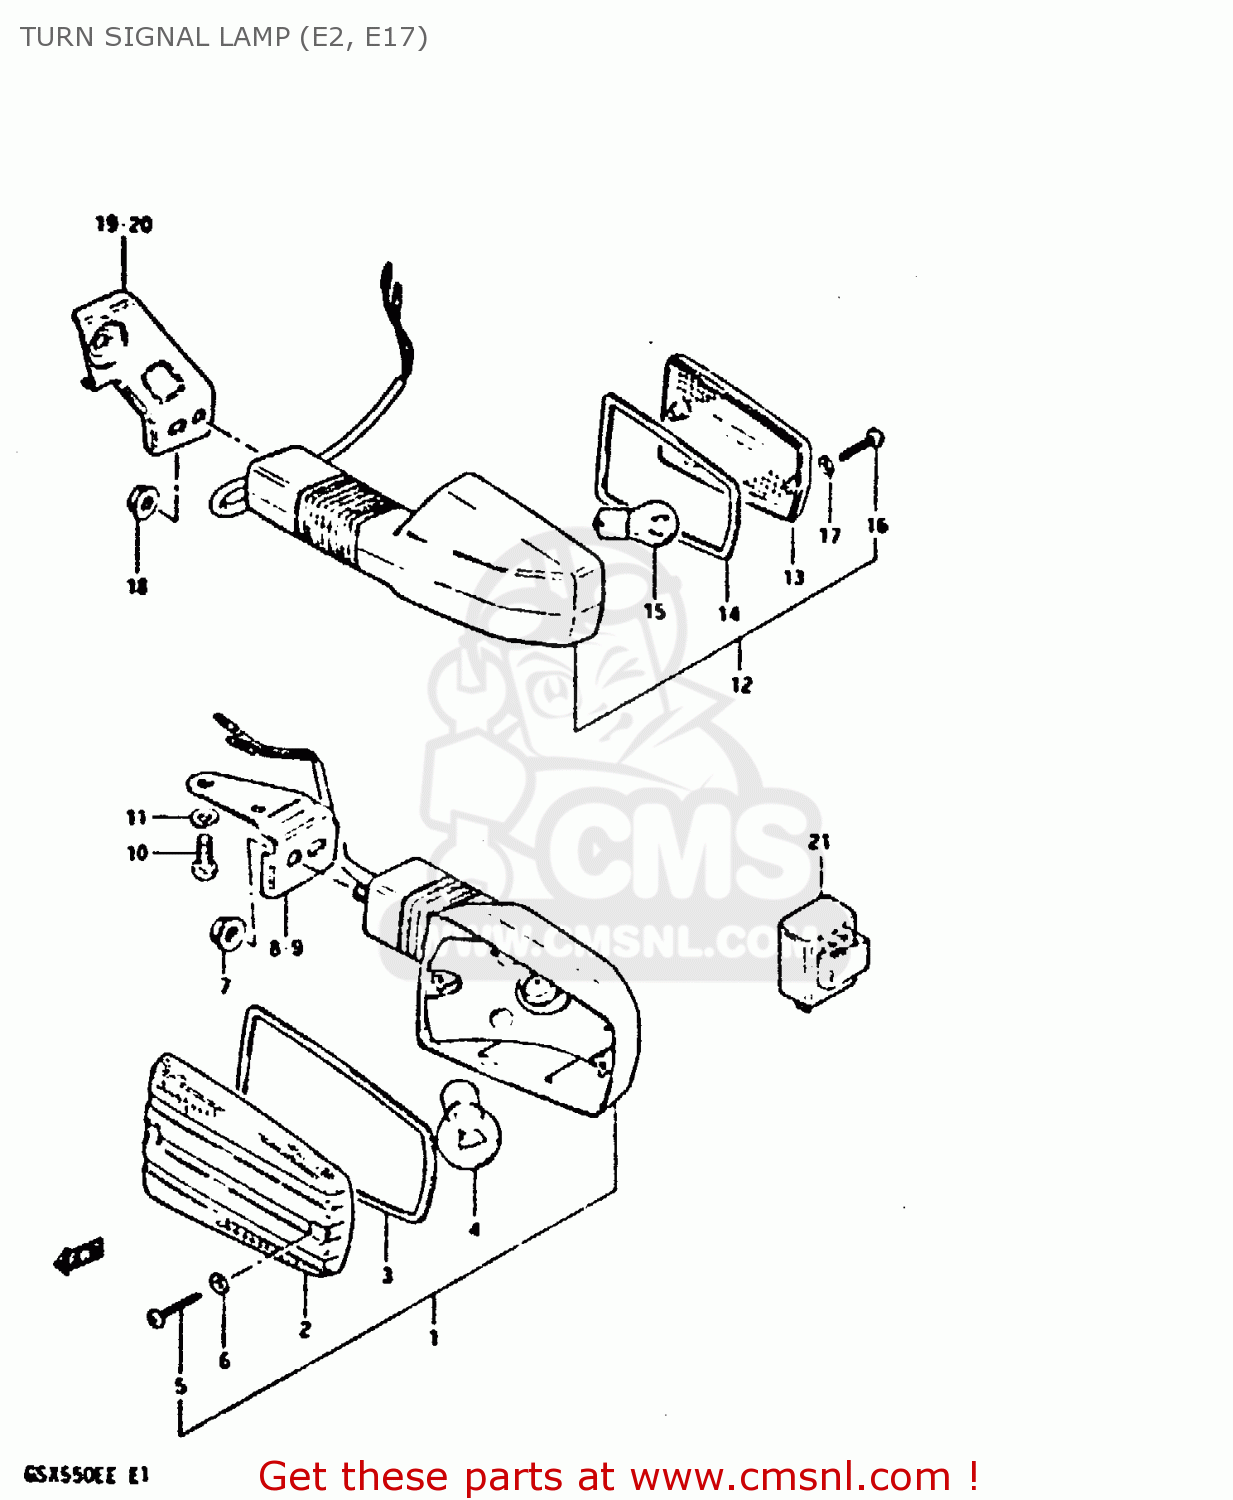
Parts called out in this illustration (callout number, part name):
1	LAMP ASSY, FRONT TURN SIGNAL
2	LENS
3	GASKET (NAS)
4	BULB(12V21W)
5	SCREW
6	GASKET (NAS)
7	NUT M8
8	BRACKET,FRONT TURN SIGNAL
9	BRACKET,FRONT TURN SIGNAL
10	SCREW
11	LOCK WASHER
12	LAMP ASSY, REAR TURN SIGNAL
13	LENS,TURN SIGN
14	GASKET (NAS)
15	BULB(12V21W)
16	SCREW
17	GASKET (NAS)
18	NUT
19	BRACKET,REAR TURN SIGNAL
20	BRACKET,REAR TURN SIGNAL
21	RELAY ASSEMBLY,TURN SIGNAL
